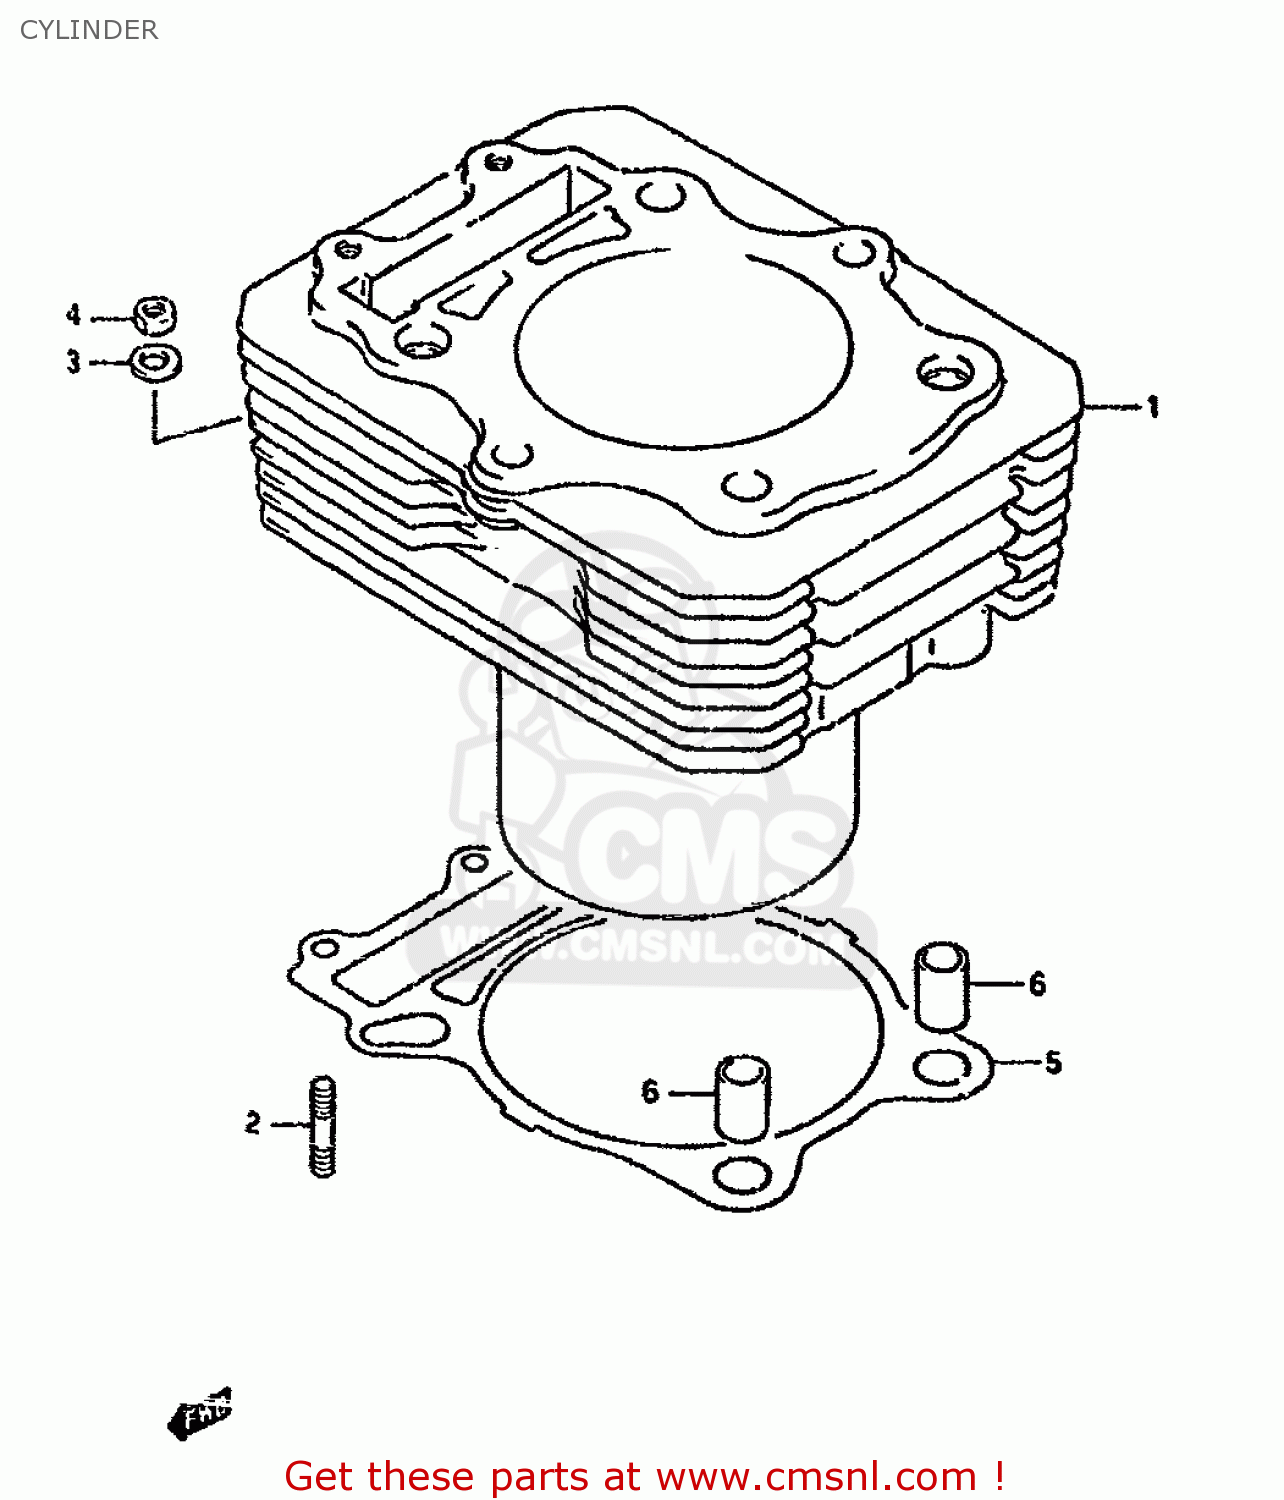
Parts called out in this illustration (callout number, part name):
1	CYLINDER
2	STUD 6X20
3	WASHER
4	NUT
5	GASKET,CYLINDER (NAS)
6	PIN
